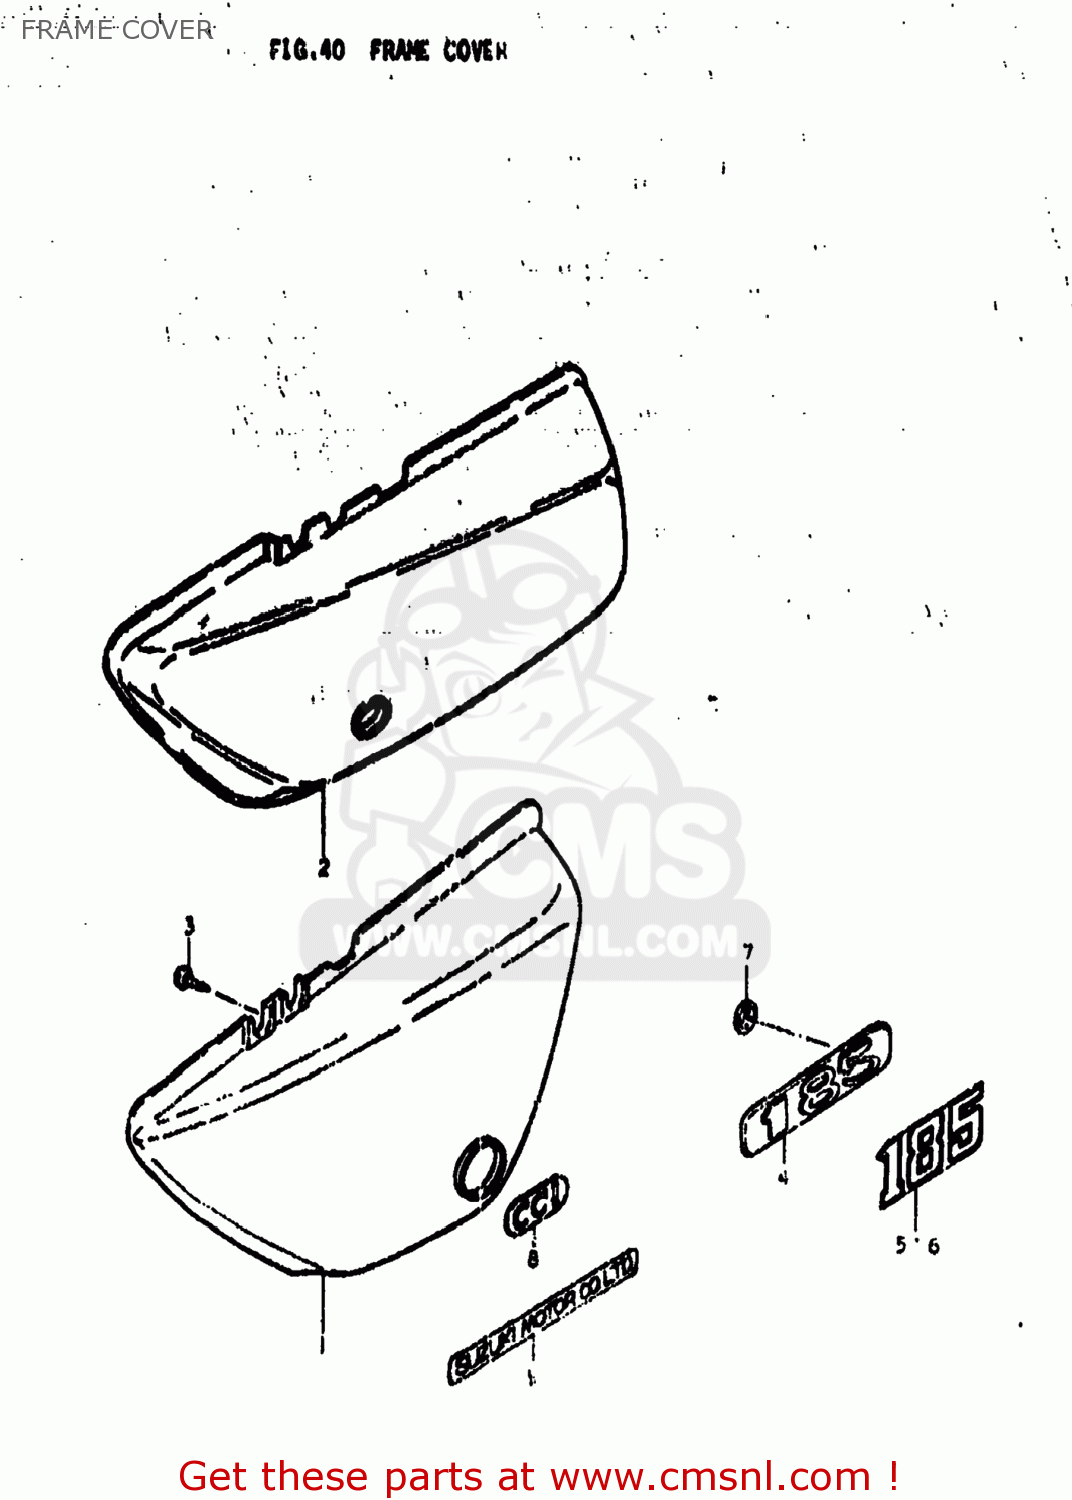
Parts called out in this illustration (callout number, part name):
1	COVER,FRAME,LEFT
2	COVER,FRAME,LEFT
3	SCREW
4	EMBLEM,FRAME COVER
5	EMBLEM,FRAME COVER
6	EMBLEM,FRAME COVER
7	NUT
8	EMBLEM,CCIS
9	LABEL,COMPANY NAME
